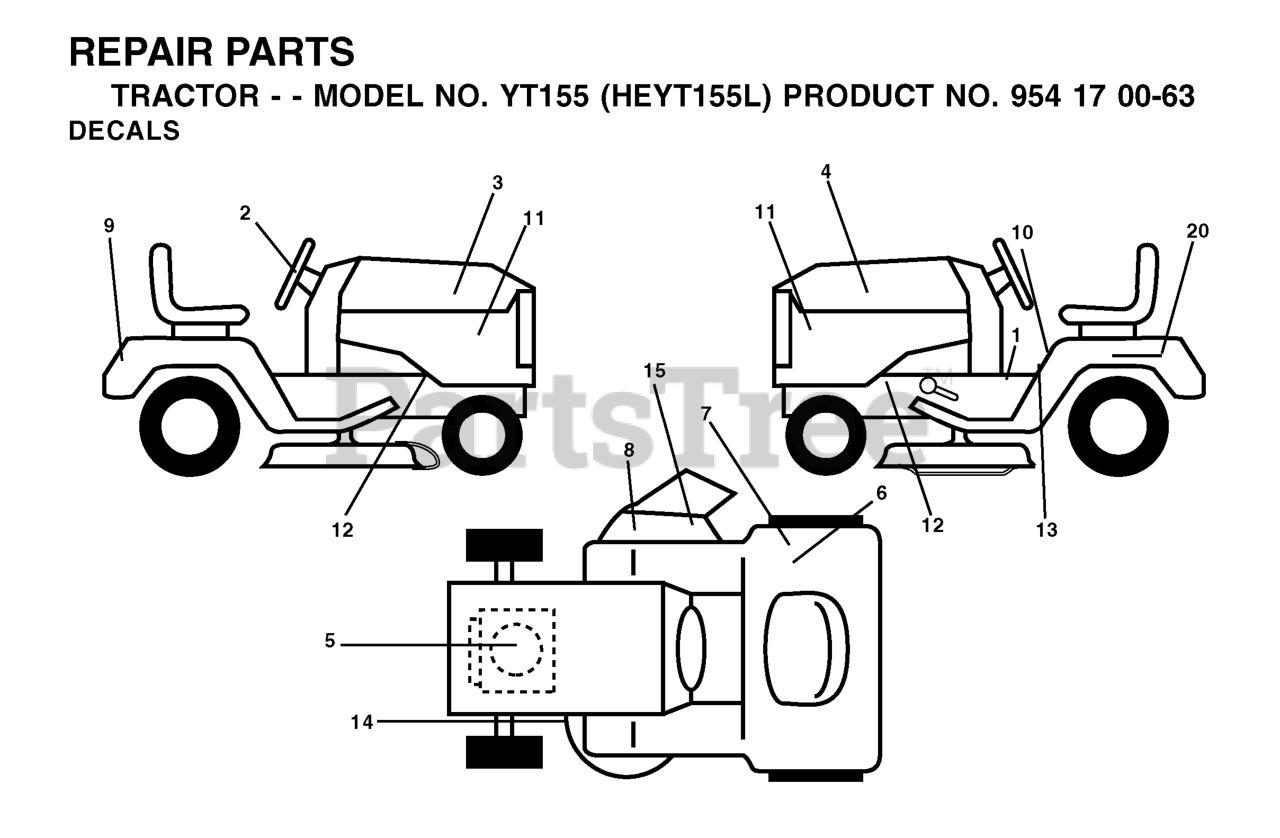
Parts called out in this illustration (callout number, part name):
1	DECAL PARK BRAKE
2	DECAL.WHEEL.STEERING.HUSQ.PERM
6	Decal, Fender 100 DB/CE
7	DECAL EUROPE STANDARD CE
8	DECAL.INTERNATIONL.CUTFINGER
9	DECAL FENDER HUSQ
10	DECAL READ OWNER'S MAN SYMS
11	DECAL PNL SIDE
13	DECAL
14	DECAL V BELT SCHEMATIC
15	DECAL DECK "B" 42"
20	DECAL BTRY SYMBOLS
